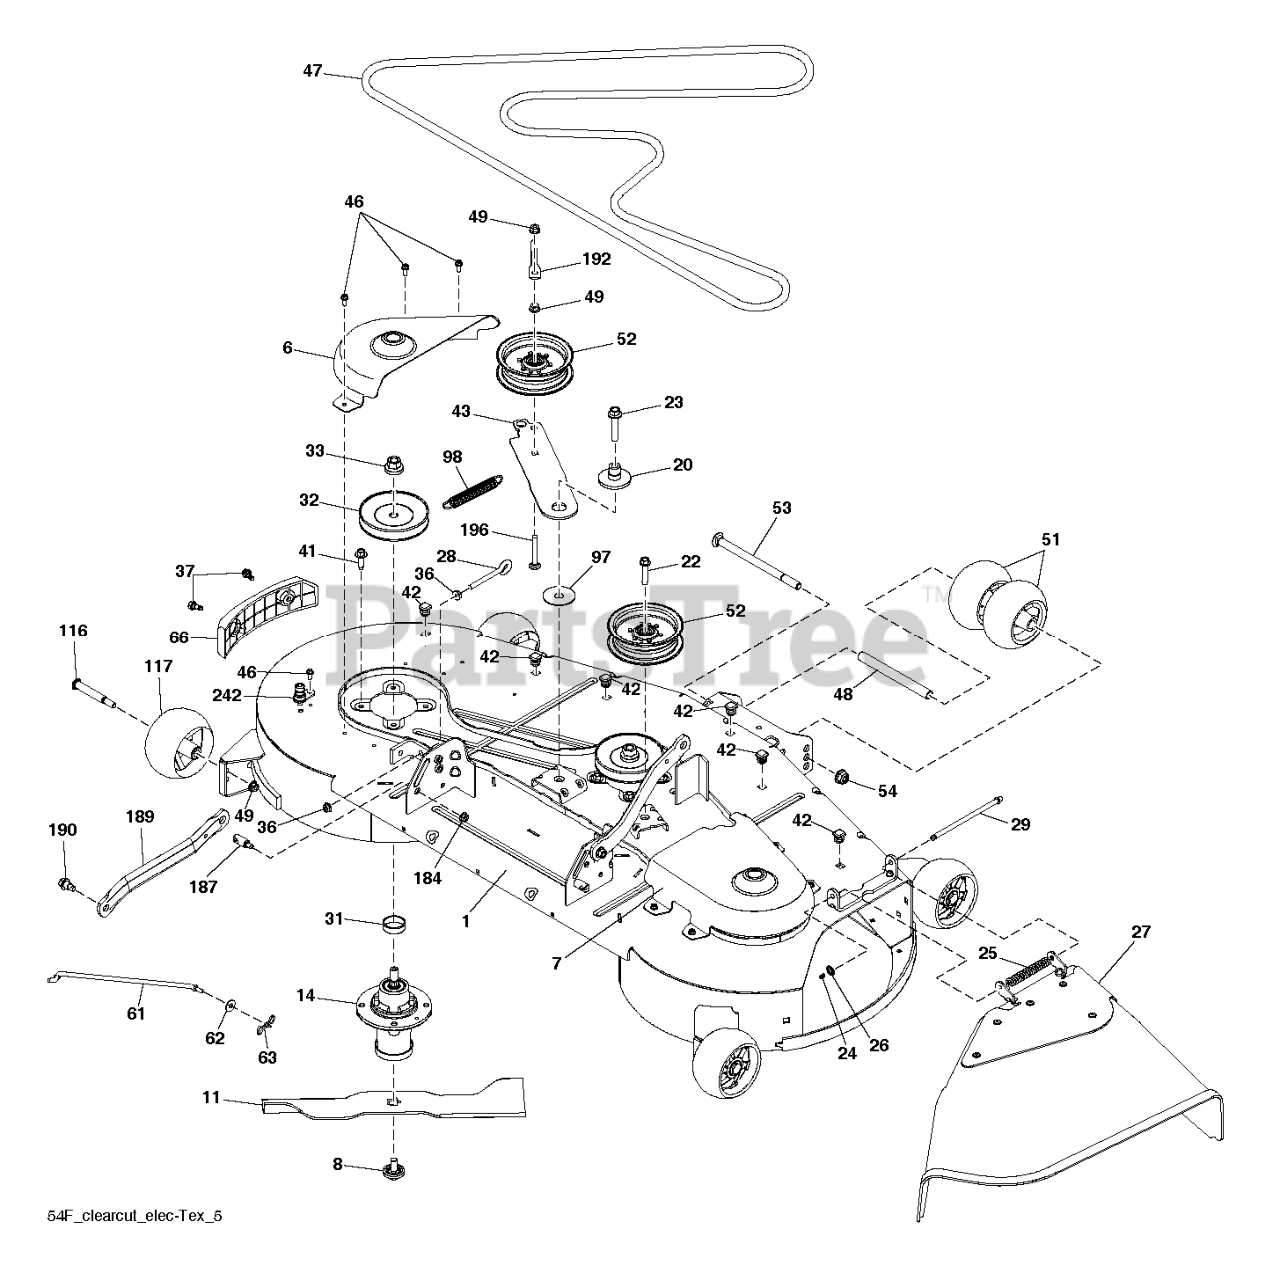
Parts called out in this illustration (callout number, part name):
1	DECK.SVC.54CC.TGB.ORANGE
6	COVER 54 CLEARCUT RH MANDREL G
7	COVER 54 CLEARCUT, LH MANDREL,
8	BOLT.WASHER.ASM.7/16-2
11	BLADE.54CC.HI-LIFT.PZ.165".668
14	MANDREL ASM, CAST IRON
20	SPACER.IDLER.PULLY.HUB
22	SCREW LT
23	SCREW.7/16-14 X 2.125.WASHER
24	CAP-SLEEVE LT
25	SPRING.42.FCS.DEFLECTOR
26	NUT PUSH M
27	DEFLECTOR ASSY 54 CLEARCUT RES
28	EYE BOLT 5/16 X 3.50
29	ROD.HINGE
31	WASHER.SPACER.MANDREL
32	PULLEY MANDREL
33	NUT.FLANGE.LOCK.TOP
36	NUT 5/16C WHIZ
37	SHOULDER BOLT 5/16-18TT
41	BOLT.HEX.WASHR.HED.313-18X1.19
43	ARM IDLER ARM, CLEARCUT 54 BLA
46	SCREW.1/4-20X5/8
47	BELT CLEARCUT 54, TRACTOR DECK
48	TUBE, ROLLER AXLE LONG
49	NUT LOCK FLG 3/8-16 UNC
51	ROLLER, GAUGE .635 BORN
52	PULLEY.IDLER.2006
53	RHSNB 1/2-13 X 8 GR5 ZD
54	NUT, 1/2-13 HEX FLG NYLOC ZD
61	ROD.ANTI.SWAY.48/54"TE
62	WASHER
63	PIN.COTTER.5/16.BOW TI
66	BUMPER ASSY 54 CLEARCUT TRIM S
98	SPRING.EXTN.42.FCS.TR.DECK.DRV
116	BOLT.SHOULDER.3/8-16X3-5/8.
117	WHEEL.GAUGE.RALLY
184	NUT LOCK HEX FLANGE 5/16-18
187	STUD.FASTNER.W/ANTI-ROTATE
189	ARM.SUSPENSION.MOWER
190	BOLT.SHOULDER
192	KEEPER.BELT.IDLER.54"T
196	BOLT
242	PORT.WASHOUT
